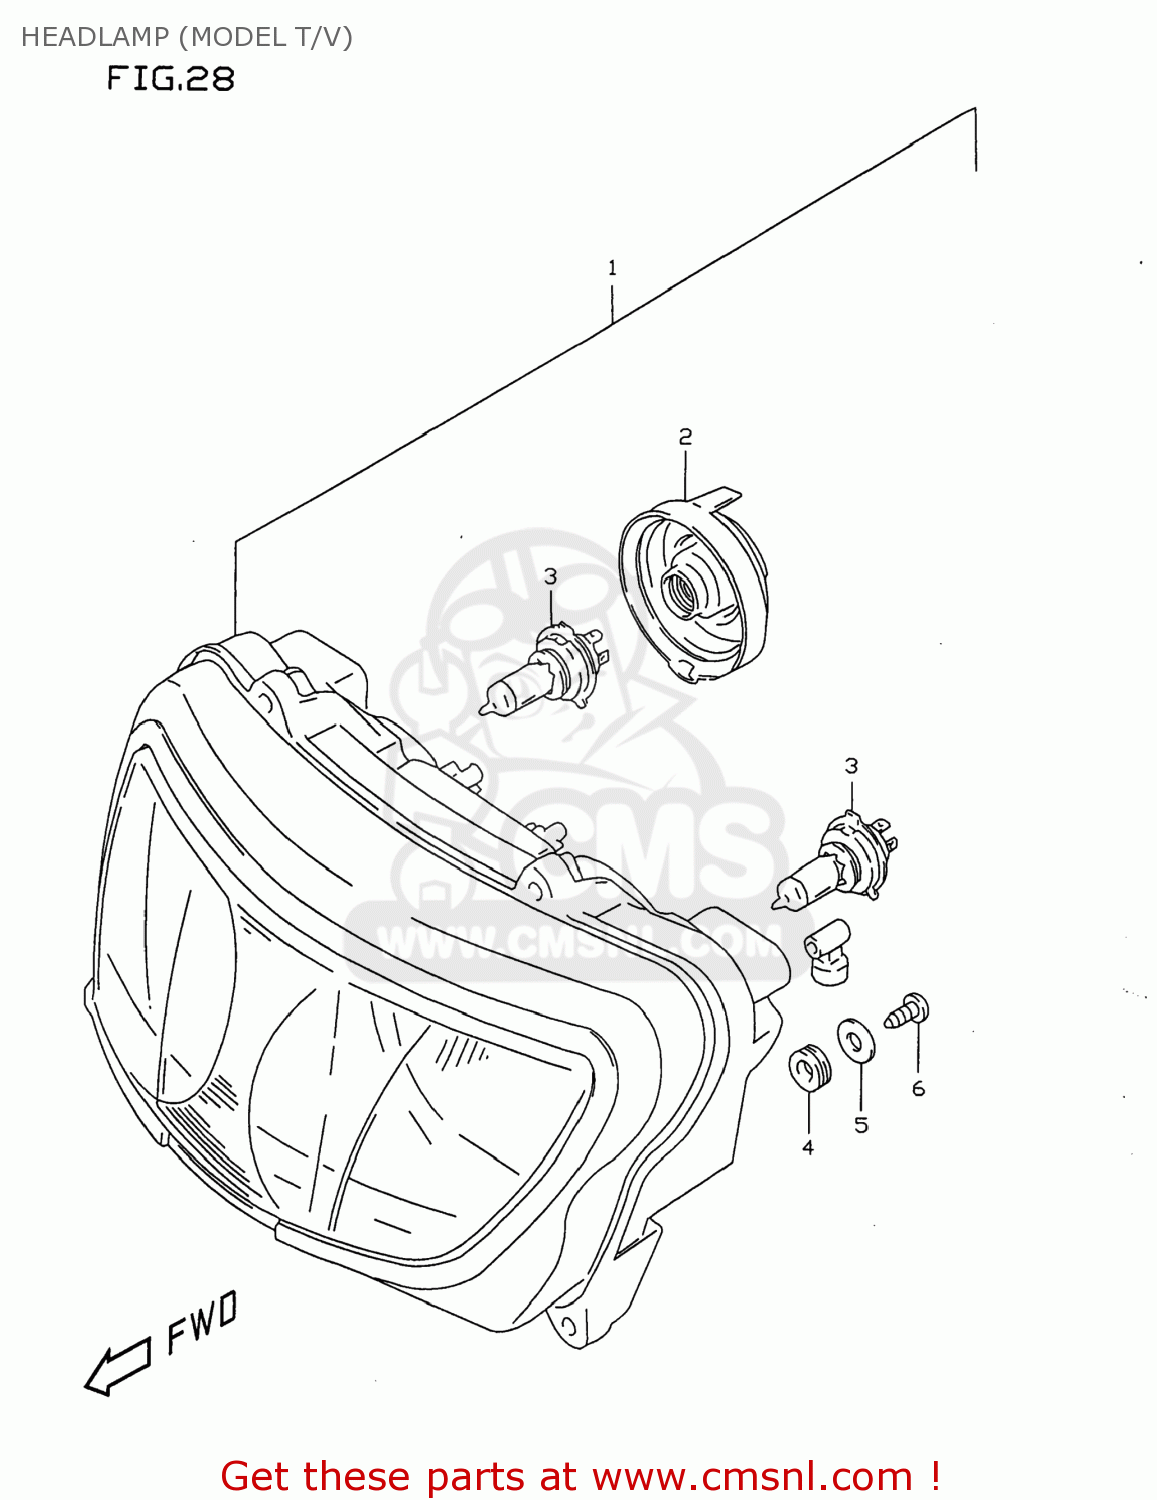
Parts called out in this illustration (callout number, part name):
1	HEADLAMP ASSY
2	COVER,SOCKET
3	BULB(12V55/50W)
4	CUSHION,HEADLAMP
5	WASHER (5.5X18X1)
6	SCREW,SIDE HOL
